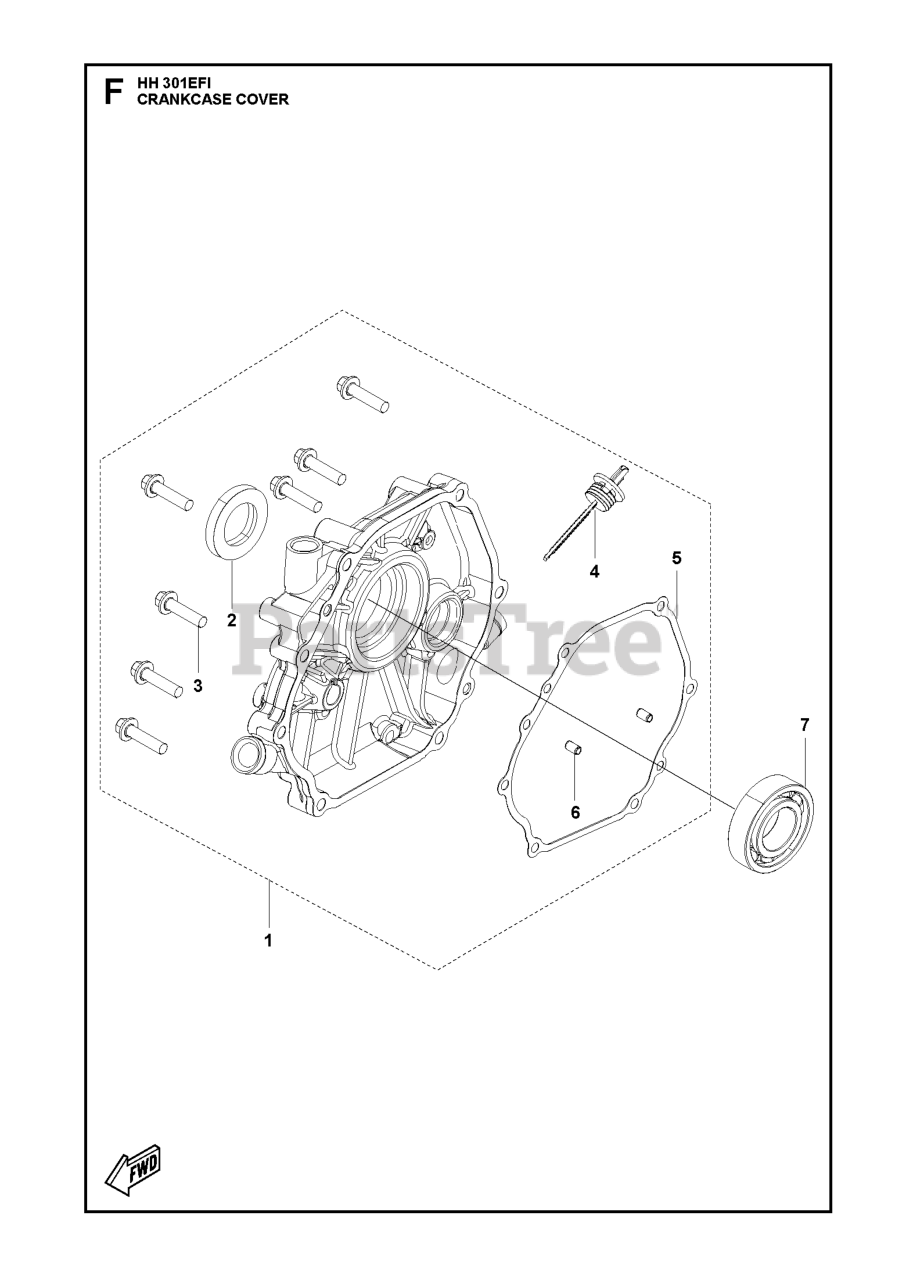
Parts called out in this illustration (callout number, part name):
1	COVER KIT CRANKCASE COVER
2	SEAL OIL SEAL
3	BOLT
5	GASKET CRANKCASE COVER GASKET
6	PIN LOCATION PIN
7	BALL BEARING
